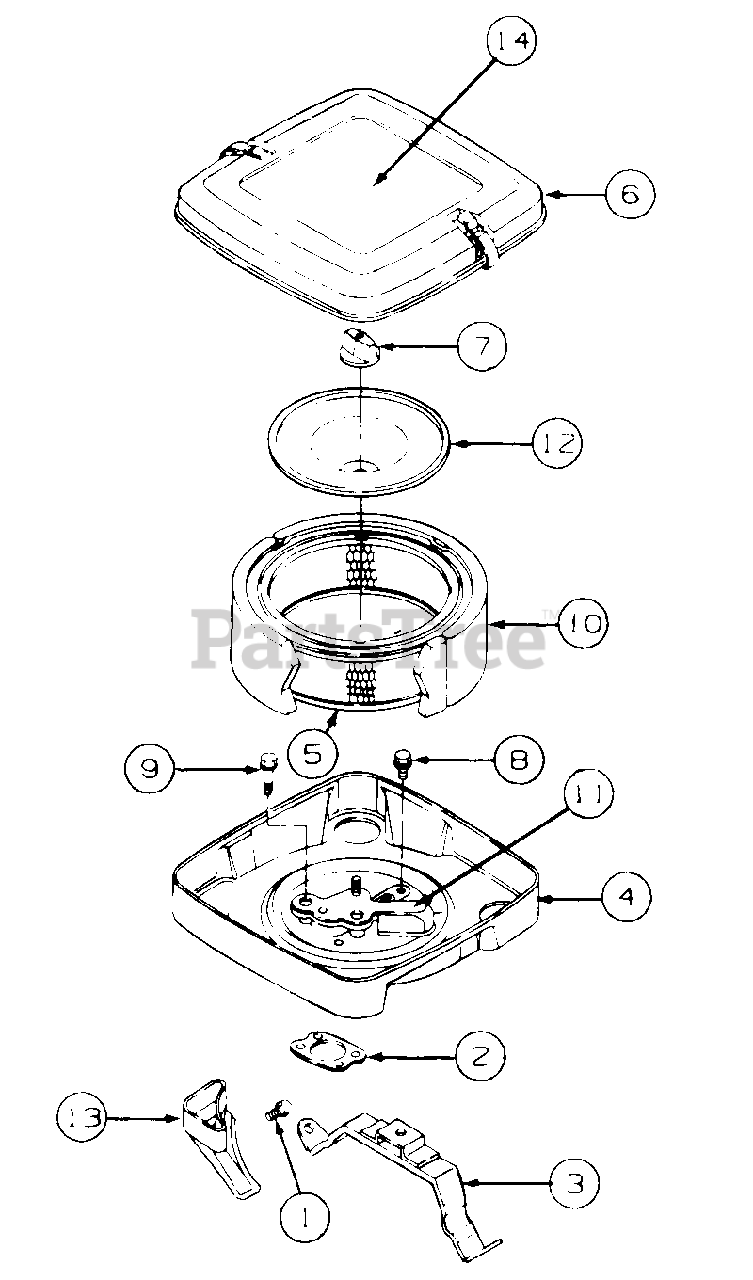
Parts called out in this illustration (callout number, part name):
1	Screw, Sems
2	Gasket, Air Cleaner
3	Bracket, Air Cleaner
4	Base, Air Cleaner
5	Cartridge, Air Cleaner
6	Cover, Air Cleaner
7	Knob, Air Cleaner
8	Screw, Sems
9	Screw, Sems
10	Element, Foam
11	Shield Assy
12	Plate, Air Cleaner
13	Tube, Air Inlet
14	Label, V-Twin Engine
